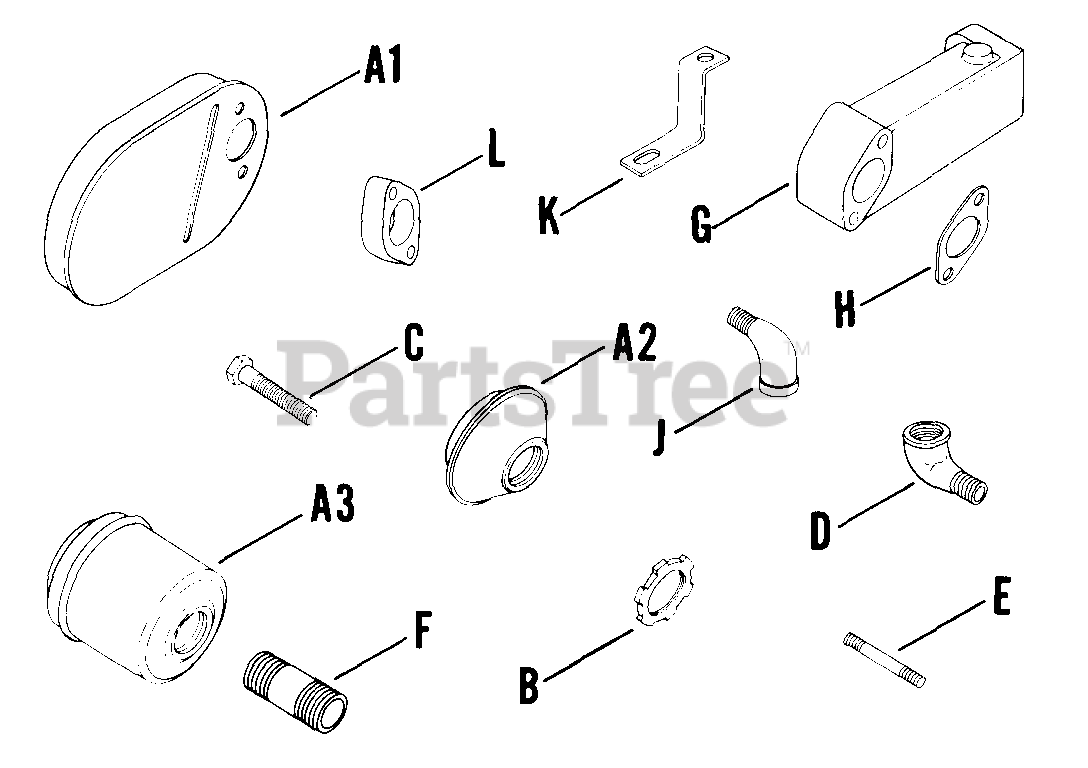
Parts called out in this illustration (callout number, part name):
A1	MUFFLER
E	STUD,1/4-20x1-7/8" - DISCONTINUED
H	GASKET - (#DSC)
